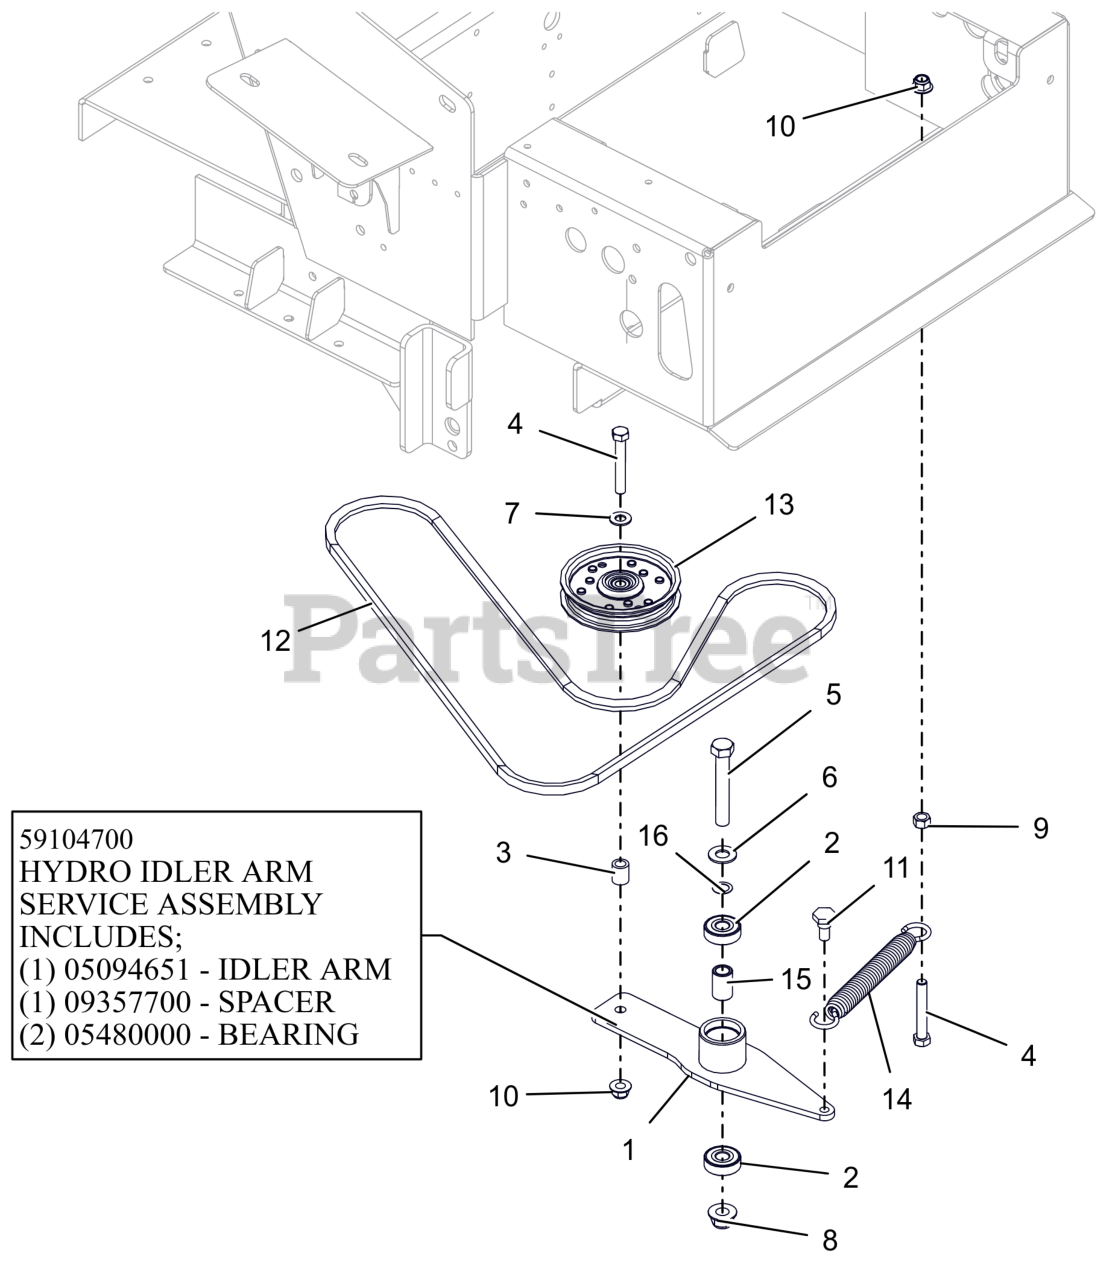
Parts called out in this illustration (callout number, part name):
1	HYDRO DRIVE IDLER ARM WMT-BLK
1	HYDRO IDLER ARM ASSEMBLY
2	BRG-BALL .500X1.38X.437
3	BSHG-SLV .407X.625X.750 PL
4	BLT, HEX .38-16X2.50 G5 ZCC
5	BLT,HEX .50-13X3.25 G5 ZCC
6	WSHR, FLT .557X1.040X.102 ZCC
7	WSHR,FLT .406X.812X.065 ZCC
8	NUT,NYL-FLG .50-13 GF ZCC
9	NUT-STD .375-16 G2 ZCC
10	NUT,NYL-FLG .38-16 GF ZCC
11	BLT,SHLDR EP .38-16X.30 HEX YZ
12	V-BELT, A-COGGED
13	ASM, 4" IDLER (.75 WIDE)
14	SPRING- EXTENSION
15	SPACER .510 X .867 X 1.1485
16	WASHER, .500X.750X.020 THRUST
